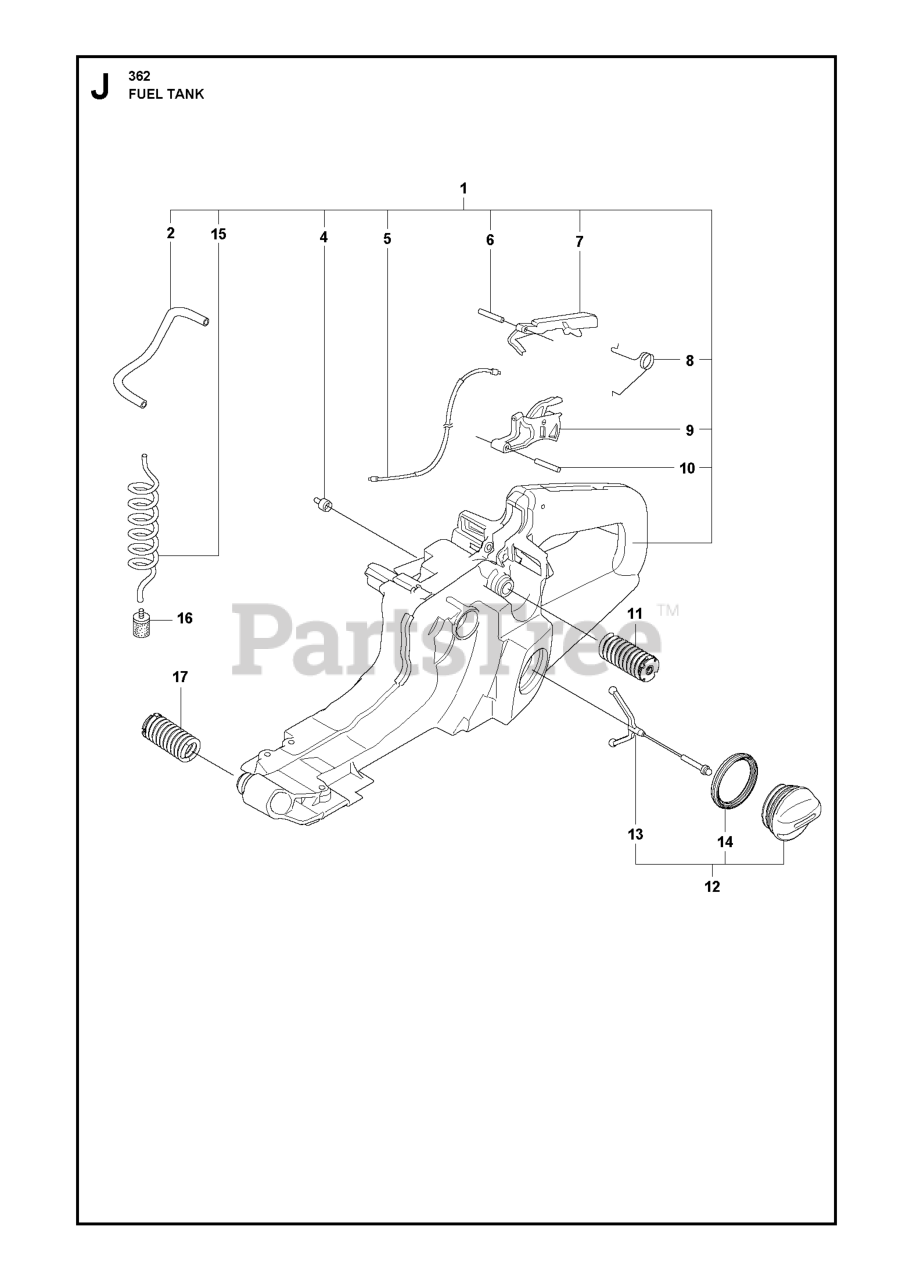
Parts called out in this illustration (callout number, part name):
2	FUEL HOSE STRAIGHT 105
3	CONNECTOR
4	FUEL TANK VENT
4	TANK VALVE
6	PIN 3X25
7	THROTTLE CATCH
9	THROTTLE TRIGGER
10	PIN CPH8 4X20
11	ANTIVIBE MOUNT
15	FUEL HOSE SPIRAL 300
16	RP FUEL FILTER
17	ANTIVIBE MOUNT
17	AV SPRING (HARD)
